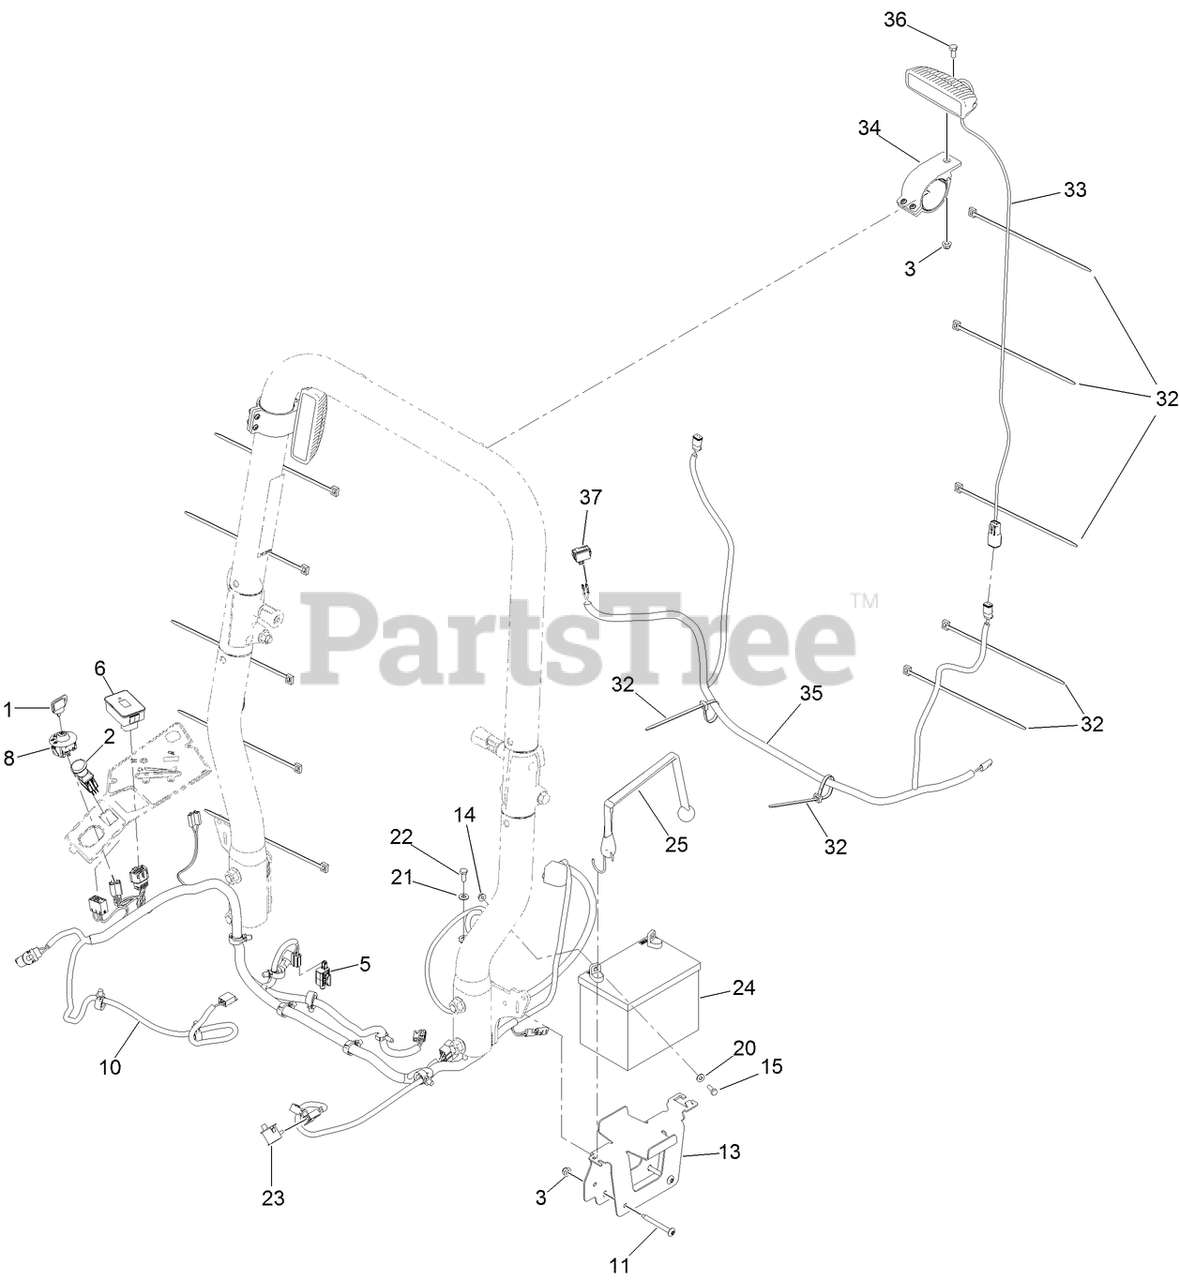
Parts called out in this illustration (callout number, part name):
1	KEY-IGNITION
2	SWITCH-PTO
3	NUT-HF, NI
5	SWITCH
6	MODULE ASM
8	SWITCH-IGNITION
10	HARNESS-WIRE
11	SCREW-TORX
13	TRAY-BATTERY
14	NUT-HF
15	SCREW-HH
20	WASHER-FLAT
21	WASHER-PLAIN
22	SCREW-HH
23	SWITCH-BAIL
24	BATTERY
25	STRAP-BUNGEE
32	TIE-PLASTIC
33	LIGHT-LED
34	CLAMP-TUBE
35	HARNESS-WIRE
36	SCREW-HH
37	SWITCH-ROCKER
